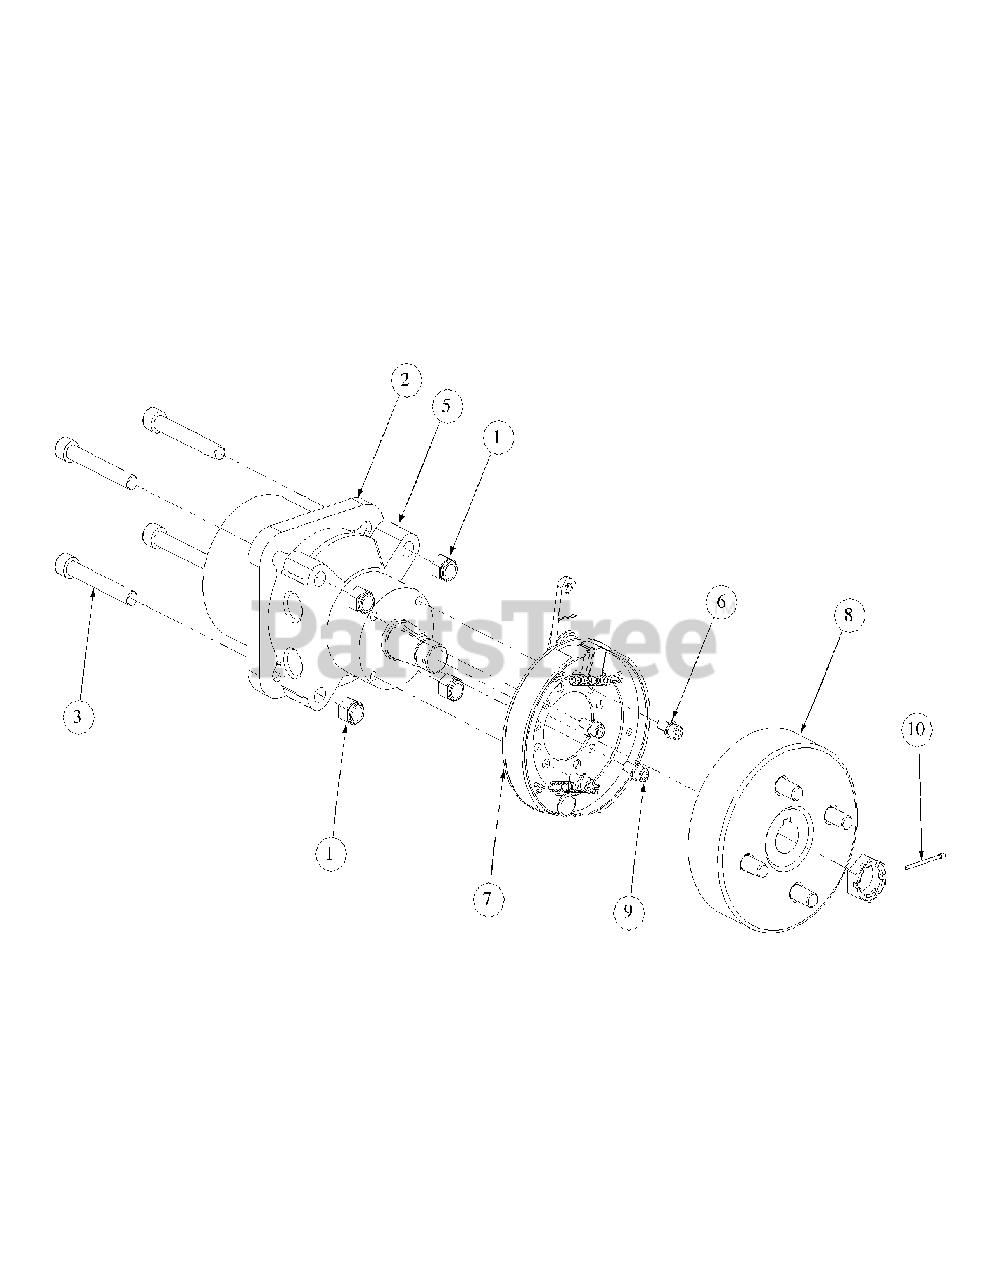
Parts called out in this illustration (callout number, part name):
1	Lock Nut, Nylon Insert, 1/2-13
2	Motor Spacer
3	Socket Head Capscrew, 1/2-13; 6-1/2
5	Hyd. Motor, Parker Left Hand Assembly w/Brake
5	Hyd. Motor, Parker Right Hand Assembly w/ Brake
6	Lock Washer, 5/16
7	Brake Assembly w/Line
8	Hub and Drum Assembly w/Studs
9	Capscrew w/Socket, 5/16-18 x 3/4
10	Cotter Pin 1/8 x 1-1/2
